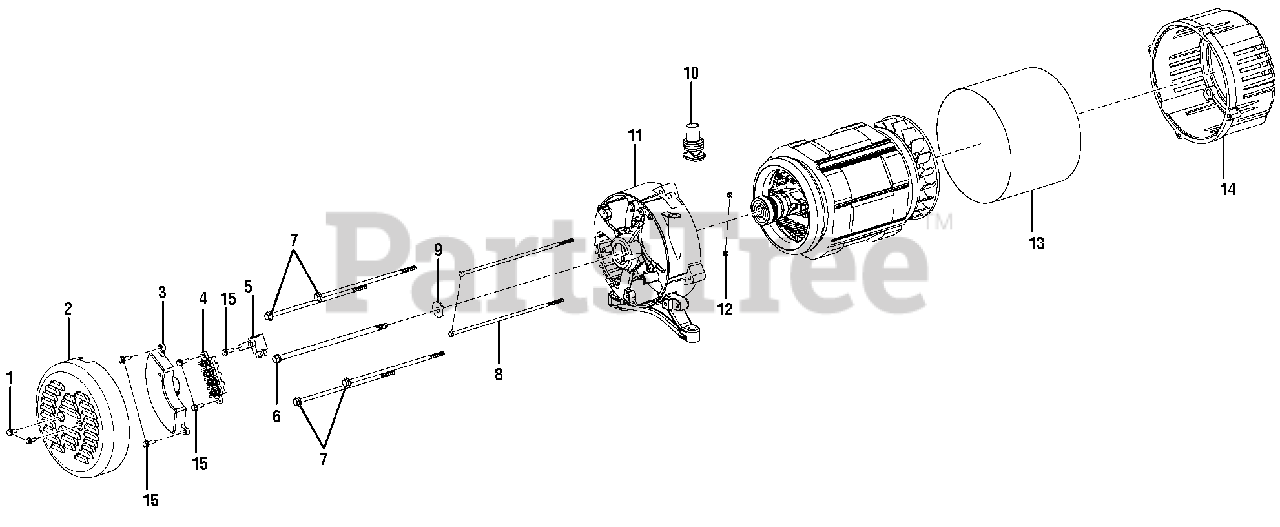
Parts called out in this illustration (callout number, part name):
1	Bolt (M5 x 12 mm, Hex Hd.)
2	Brush Cover
3	Automatic Voltage Regulator
4	Terminal Block
5	Brush Assembly
6	Bolt (5/16-24 x 235 mm, Hex Washer Hd.)
7	Bolt (M6 x 188 mm, Hex Washer Hd.)
8	Bolt (M5 x 210 mm, Hex Washer Hd.)
9	Washer (8 x 26 x 3t)
10	Rubber Boot
11	Bearing Housing
12	Hex Nut (M5)
13	Generator Head Cover
14	Adaptor Housing
15	Bolt (M5 x 16 mm, Hex Hd.)
